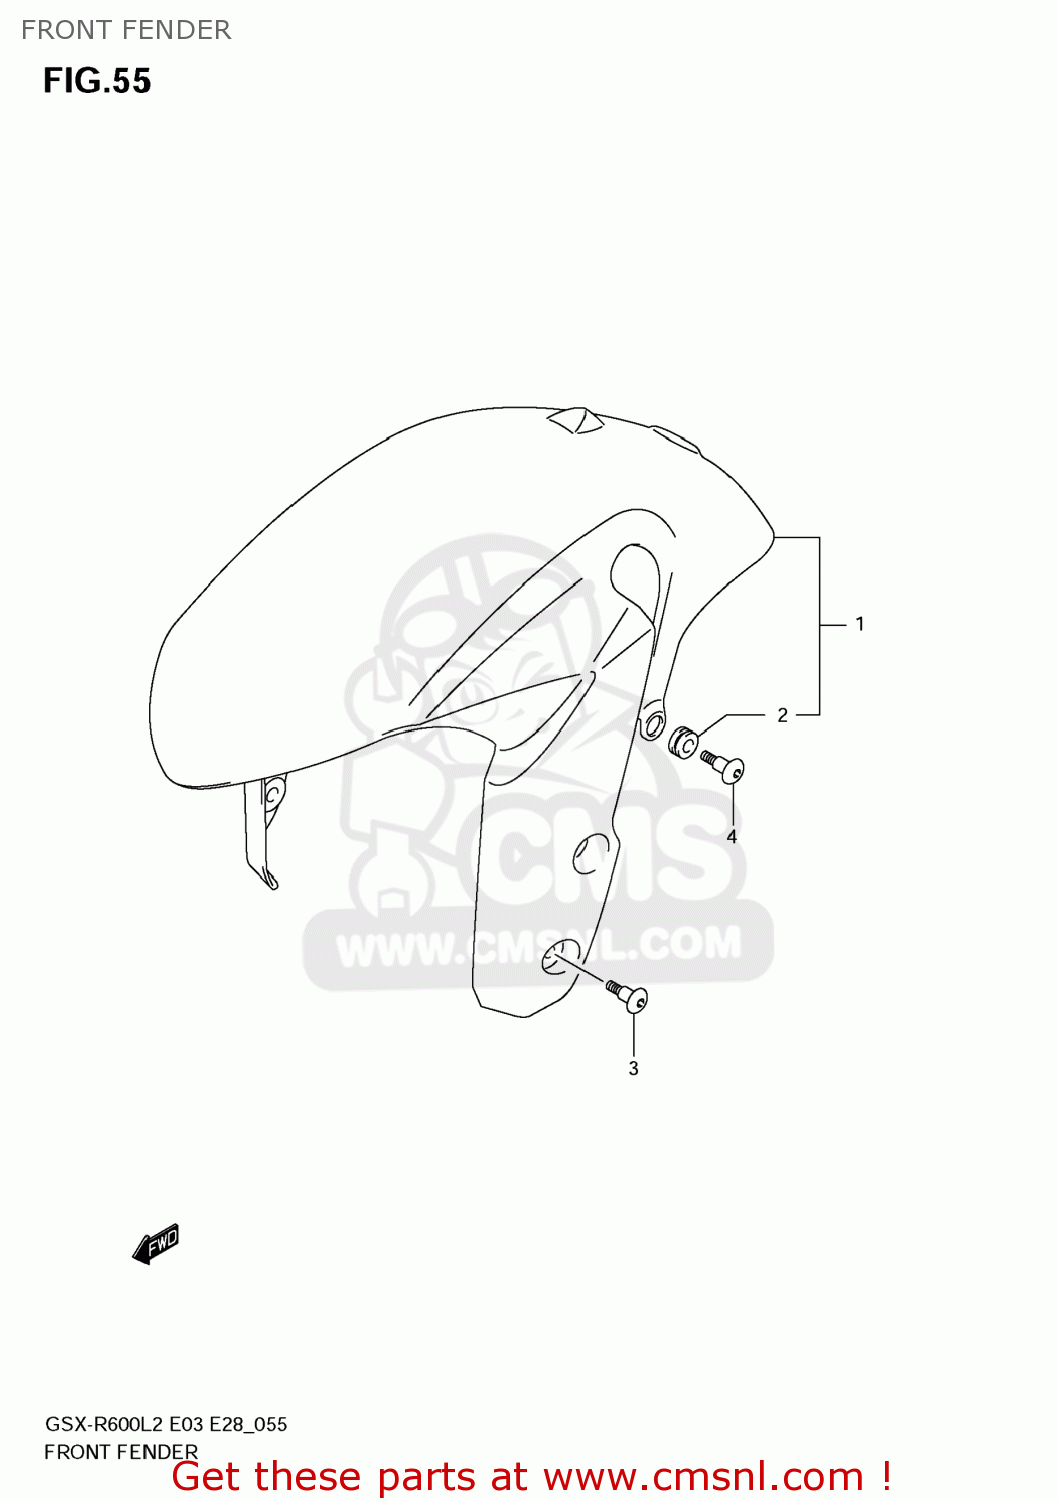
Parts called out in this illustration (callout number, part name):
1	FENDER ASSY,FR(BLUE)
2	CUSHION
3	SCREW(6X16)
4	SCREW(6X16)
